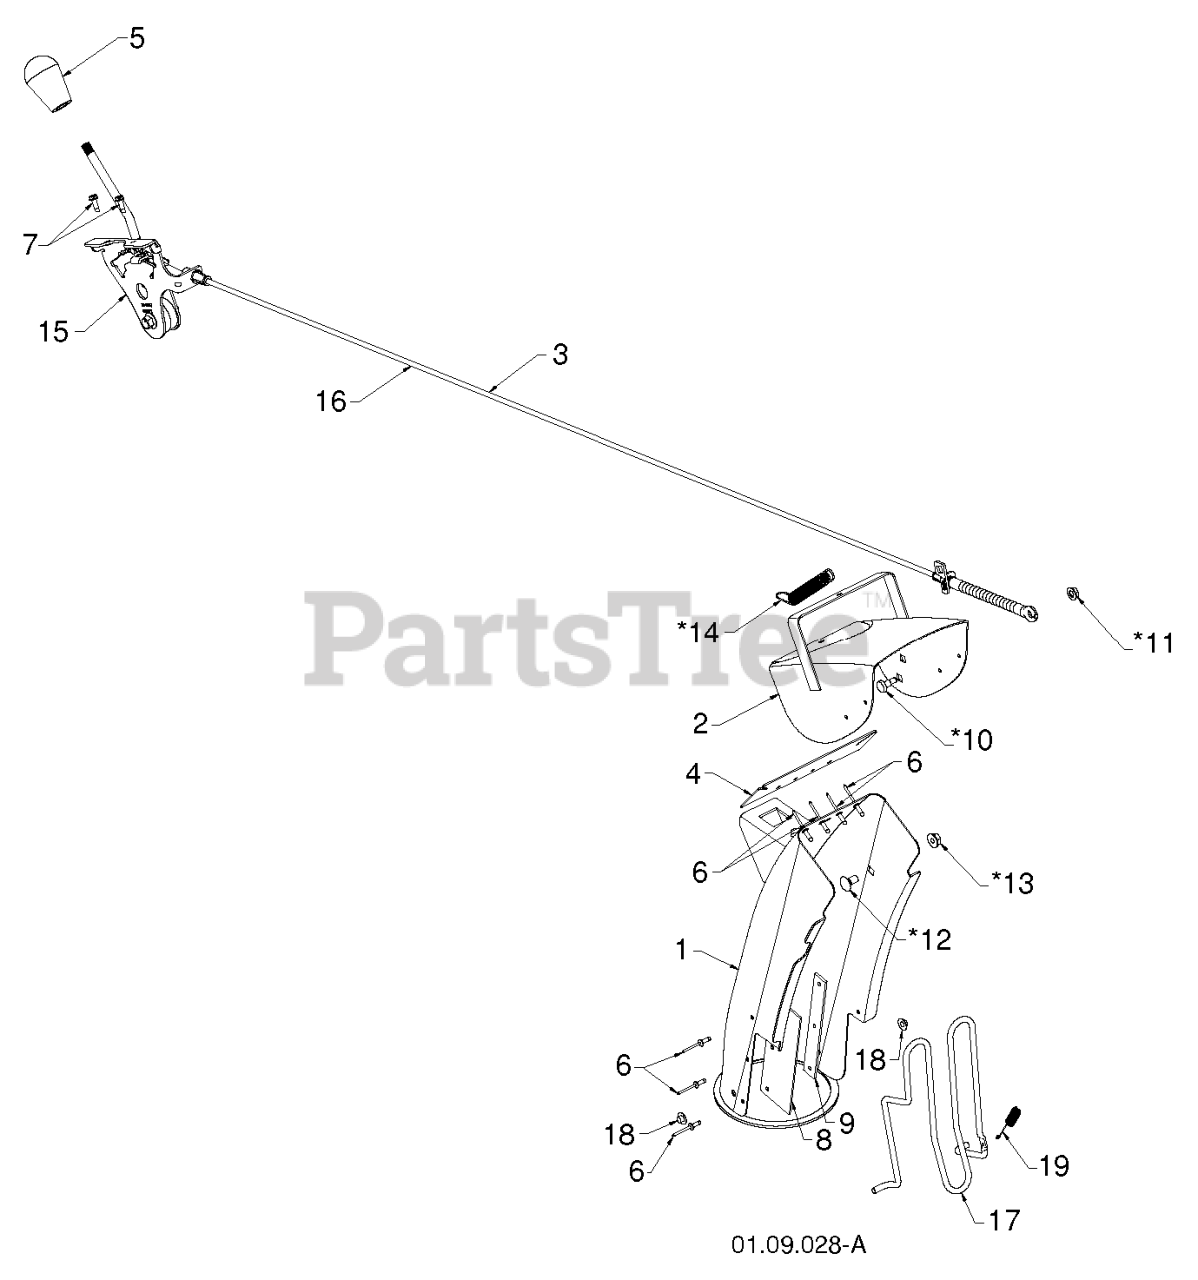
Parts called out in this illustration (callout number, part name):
1	CHUTE.WELDMENT.SNOW.ORANGE
2	DEFLECTOR.WELDMENT.PNT.ORANGE
3	RP.CONTROL.ASM.DEFLECTOR.SNOW
4	SEAL.DEFLECTOR
5	KNOB LEVER, BLACK
6	RIVET BLIND
7	SCREW #10-24 X 5/8
8	SHIELD.SNOW.CHUTE
9	STRAP.SHEILD.RETAINER
15	RP CNTRL.HEAD.ASSEM.DEFLECTOR
16	RB SERVICE.CHUTE.DEF.CBL.BLK
17	ROD.GUARD.CHUTE (2 2)
18	NUT
19	SPRING.CHUTE.GUARD
